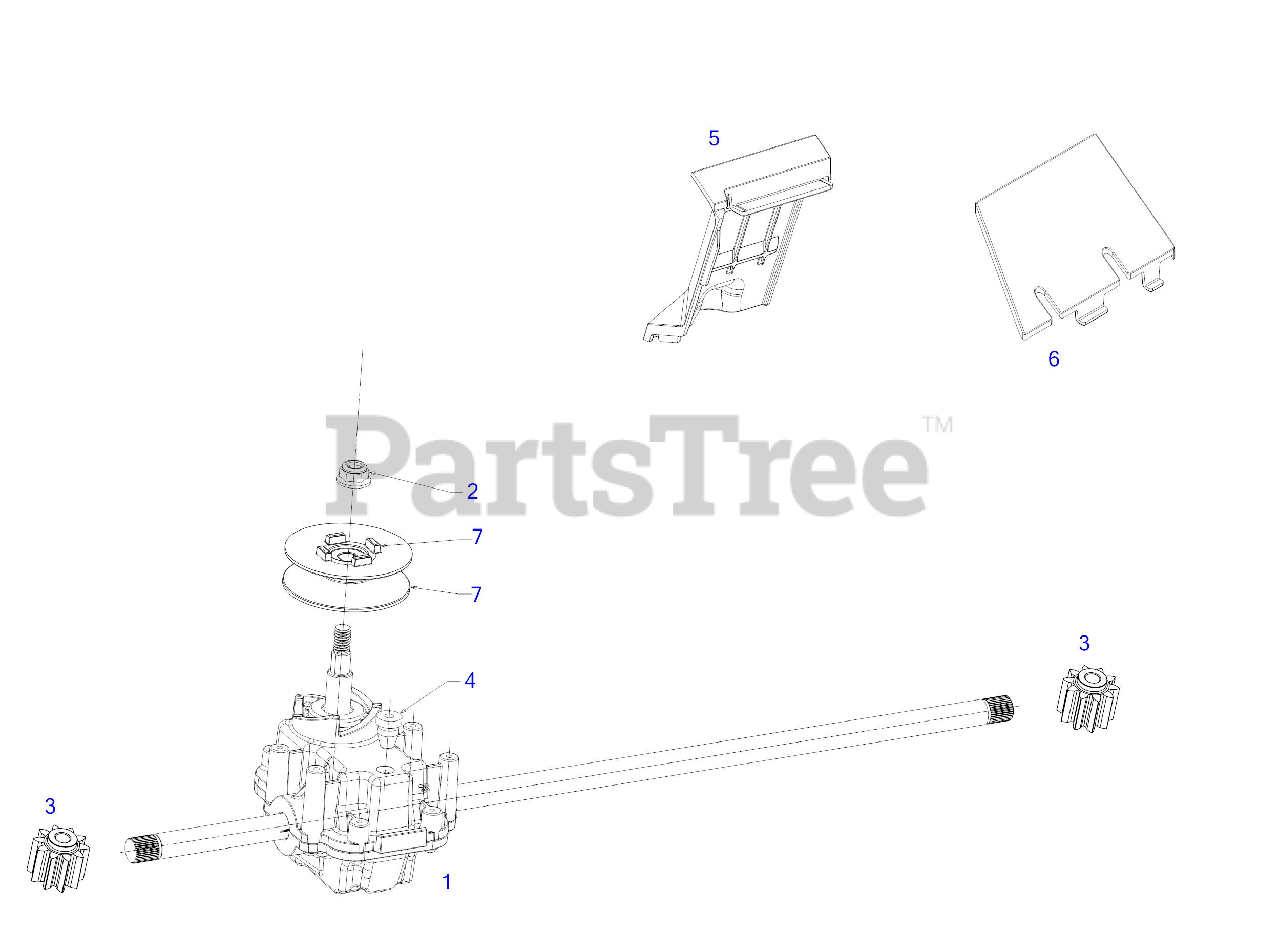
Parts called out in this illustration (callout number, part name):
1	TRANSMISSION ASSEMBLY
2	FLANGE LOCK NUT 5/16-18
3	SPUR GEAR 10T
4	RUBBER PLUG
5	TRANSMISSION COVER (FRONT)
6	TRANSMISSION COVER (REAR)
7	HALF PULLEY 2.5 OD
